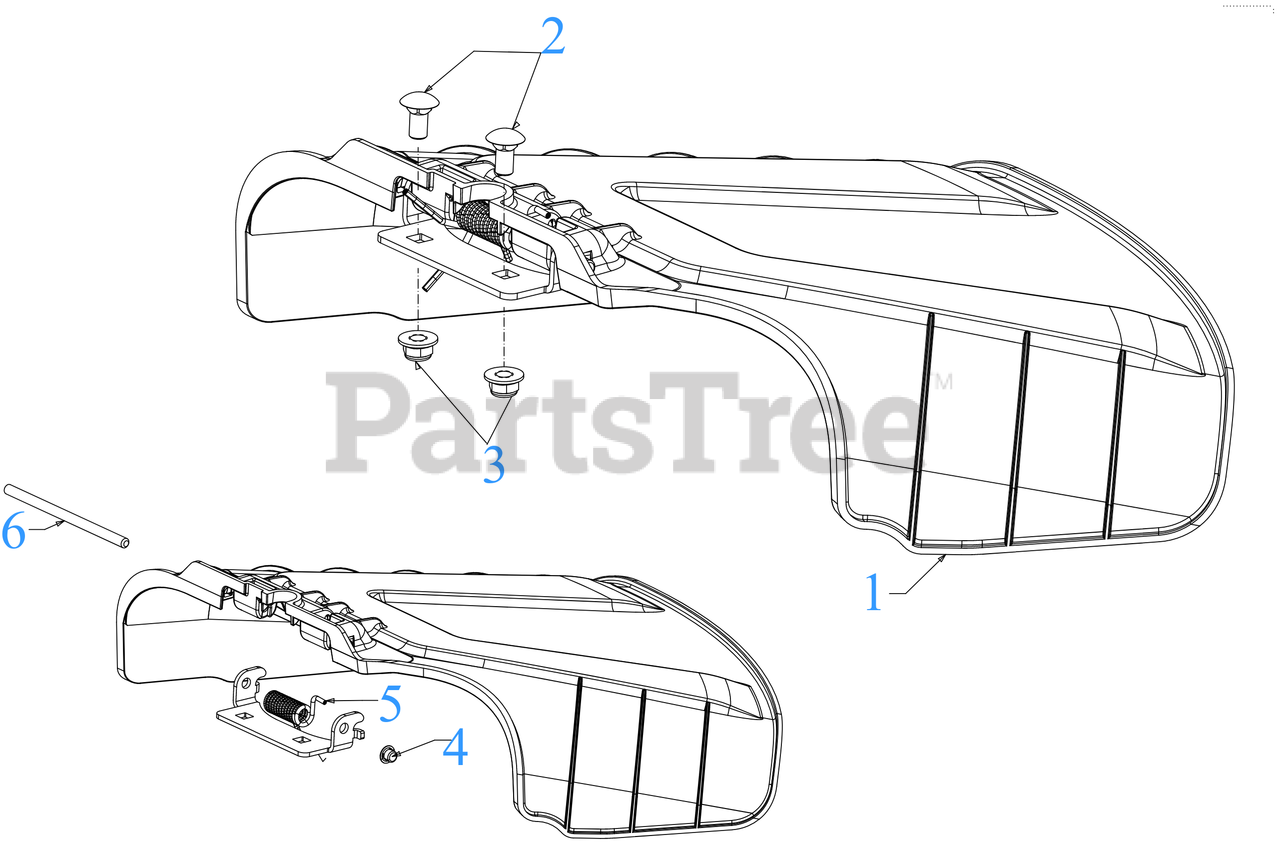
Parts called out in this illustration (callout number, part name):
1	CHUTE ASSEMBLY
2	CARRIAGE BOLT 3/8-16 x .750 GR5
4	SPEED NUT
5	TORSION SPRING
6	CHUTE HINGE PIN
